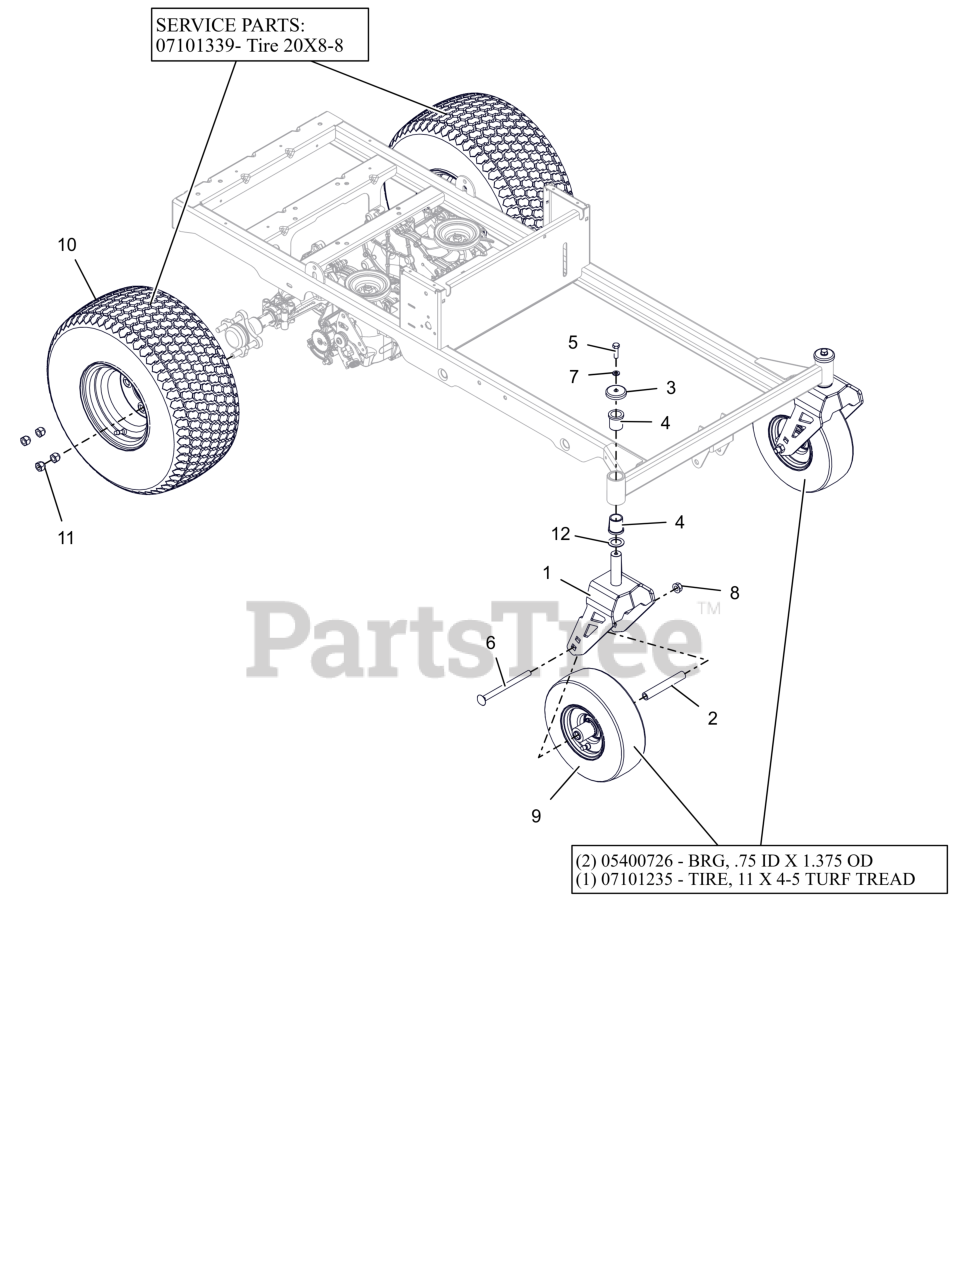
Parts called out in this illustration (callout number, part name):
1	WLDMT, CASTER FORK-XD (ORANGE)
2	SPACER, ROLLED WHEEL
3	SHIELD, AXLE BEARING
4	BSHG-FLG 1.00X1.25X1.50X1.50
5	BLT, HEX .38-16X1.25 G5 ZCC
6	BLT, RHSN .50-13X6.50 G5 ZCC
7	WSHR,LK-REG .375X.094 ZCC
8	NUT-LK-CTR-FLG .500-13 GG ZCC
9	ASM, WHL/TIRE 11X4.00-5
9	BRG, .75 ID X 1.375 OD
9	TIRE, 11X4-5 TURF TREAD
9	TUBE 11 X4.0-5
10	ASSM TIRE\WHEEL, 20 X 8 -8
10	TIRE, 20 X 8-8
11	NUT, WHEEL .50-20 ZCC
12	WSHR-HRD-THRS 1.007X1.542X.062
